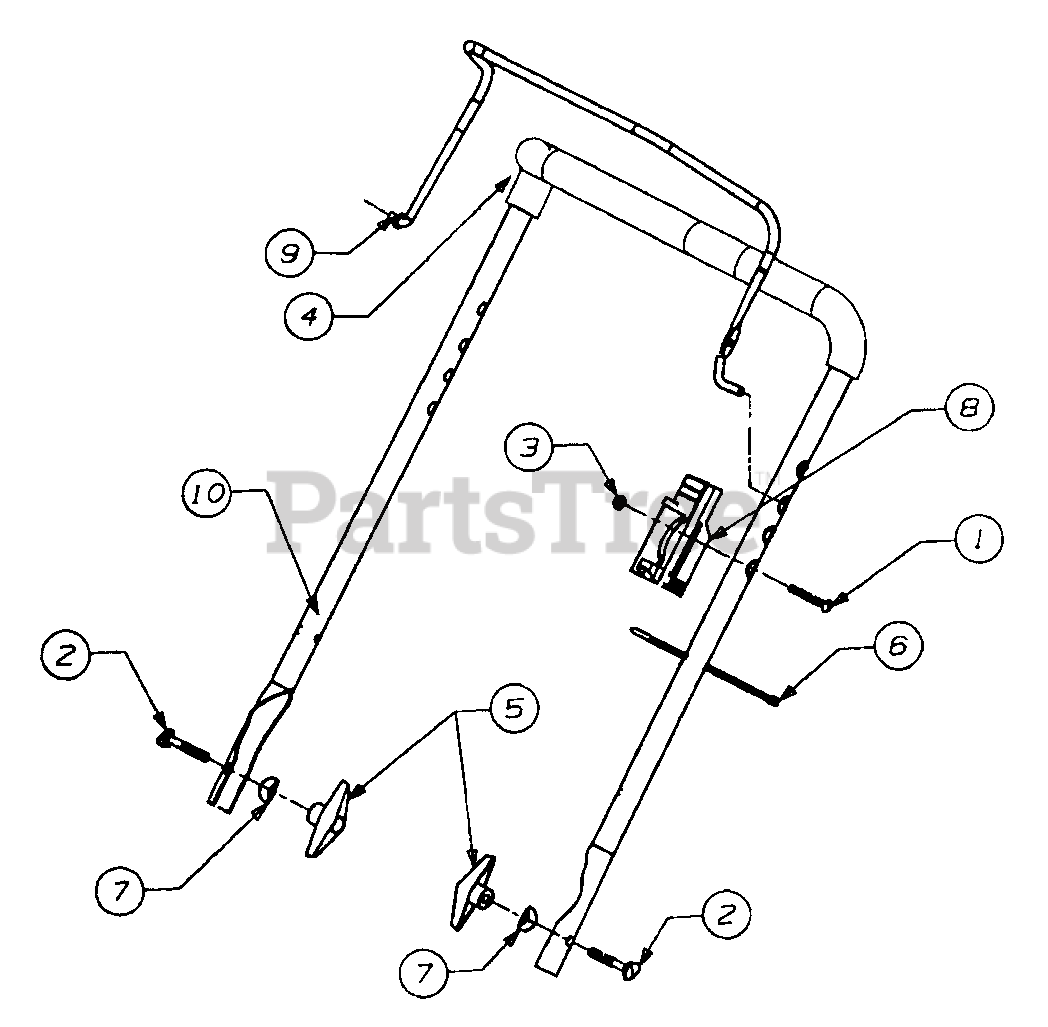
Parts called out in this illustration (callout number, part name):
1	Oval C-Sunk Screw
2	Carriage Bolt
3	Lock Nut
4	Foam Grip
5	Handle Knob
6	Cable Tie
7	Saddle Washer
8	Control Lever
